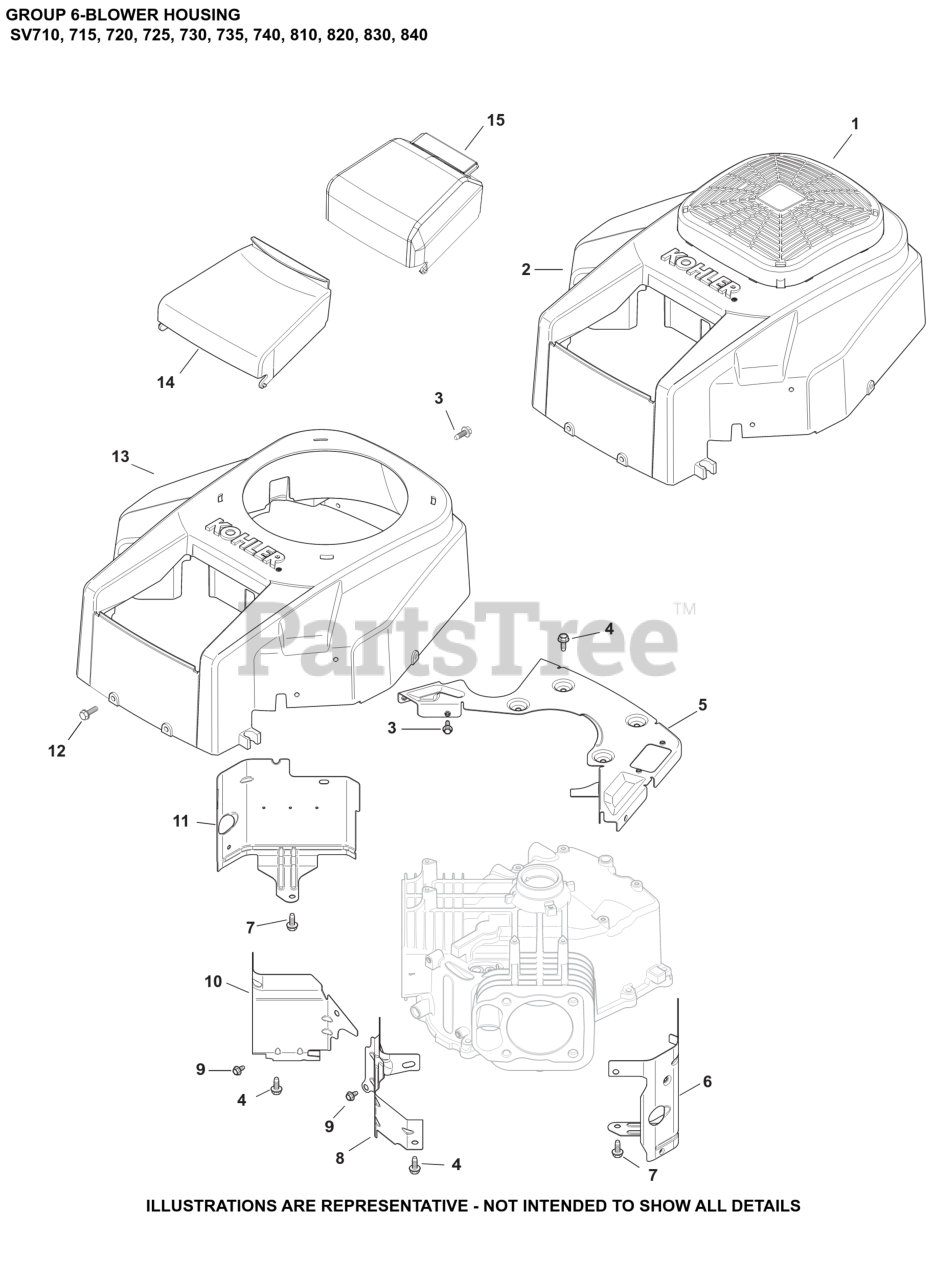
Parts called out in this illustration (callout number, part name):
2	KIT, BLOWER HOUSING-(#DSC)
3	SCREW, THREAD FORMING
4	SCREW, THREAD FORMING
5	KIT, BACKING PLATE-(#DSC)
6	BAFFLE, LEFT BARREL
7	SCREW, THREAD FORMING
8	BAFFLE, VALLEY #2 CYLINDER
9	SCREW, THREAD FORMING
10	BAFFLE, VALLEY #1 CYL-USE 24 063 114-S
11	BAFFLE, CYL BARREL - #1 SIDE
12	SCREW, TAP M6X1.7X18
14	COVER, AIR CLEANER
